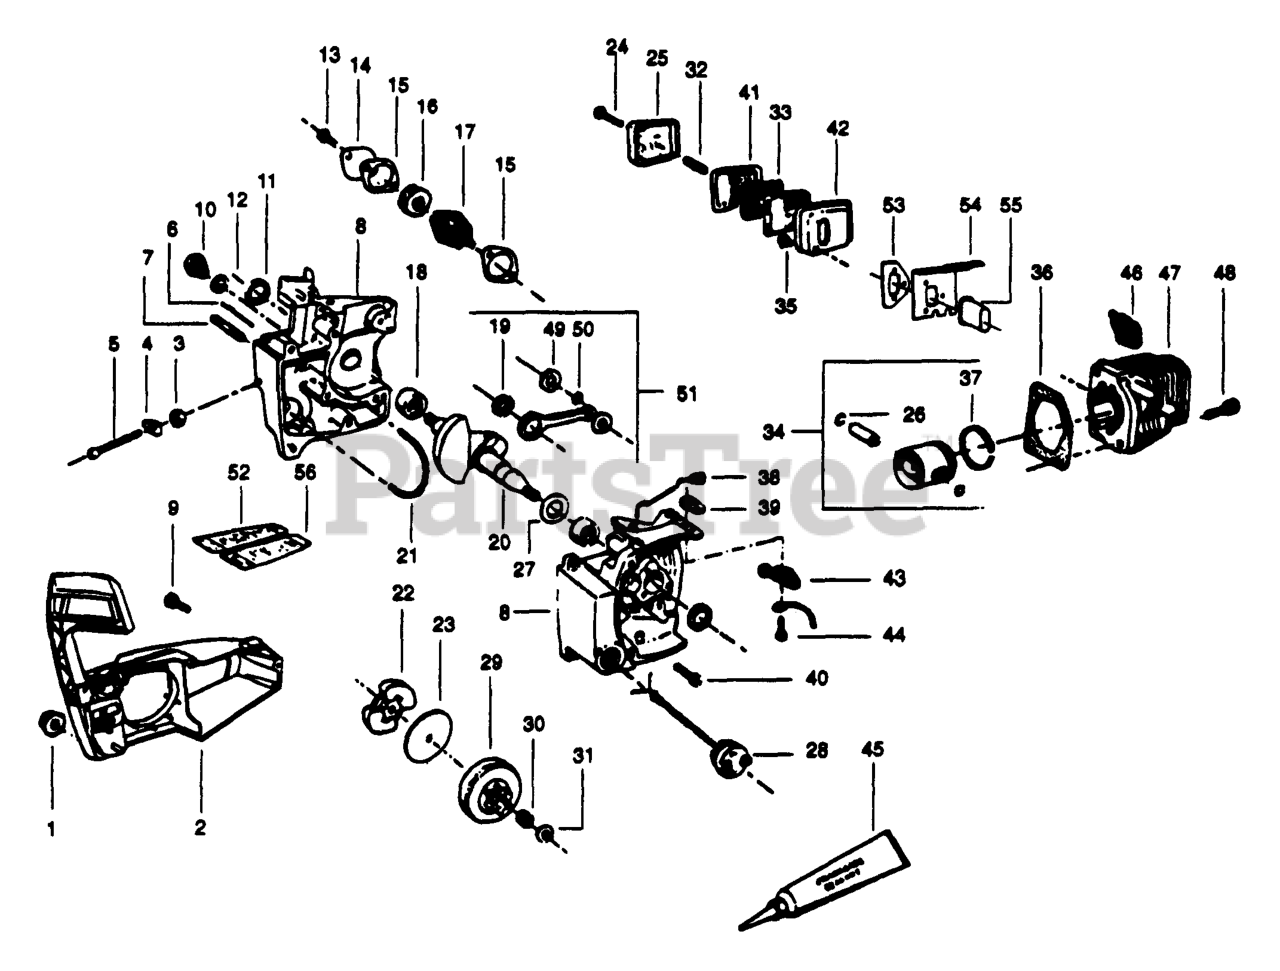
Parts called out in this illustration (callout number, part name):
1	BAR NUT
2	CHAINBRAKE ASSY
4	BAR ADJUST PIN
6	OIL TANK VENT PIN
7	BAR MOUNTING STUD
8	Crankcase Ass'y
10	CHECK VALVE KIT
11	SEAL-CRANKCASE
12	CHECK VALVE GASKET
14	METERING BODY COVER
15	METERING BODY GASKET
16	OIL FILTER
17	Metering Body Ass'y.
19	ROLLER BEARING (12 BRGS)
20	CRANKSHAFT
21	OIL DISCHARGE LINE
22	Clutch Ass'y. Kit
23	CLUTCH WASHER KIT
25	MUFFLER COVER
26	PISTON PIN RETAINER
27	THRUST WASHER
28	OIL CAP ASSEMBLY
29	CLUTCH DRUM
30	CLUTCH BEARING
31	CLUTCH SPACER
33	SPARK ARRESTOR SCREEN
34	PISTON KIT
36	CYLINDER GASKET
37	PISTON RING
38	SWITCH KNOB ASSY
39	RAMP SWITCH
41	MUFFLER BAFFLE
42	MUFFLER BODY
43	SWITCH CLAMP
45	RTV 3.35 OZ #598B
46	Spark Plug
48	SCREW-1/4-20 X 13/16
50	BEARING ROD (1 PACK OF 24)
51	CONNECTING ROD ASSY
52	Instruction Decal Right Hand
53	GASKET, MUFFLER
54	BACK PLATE, MUFFLER
55	HEAT INSULATOR
56	Instruction Decal Left Hand
